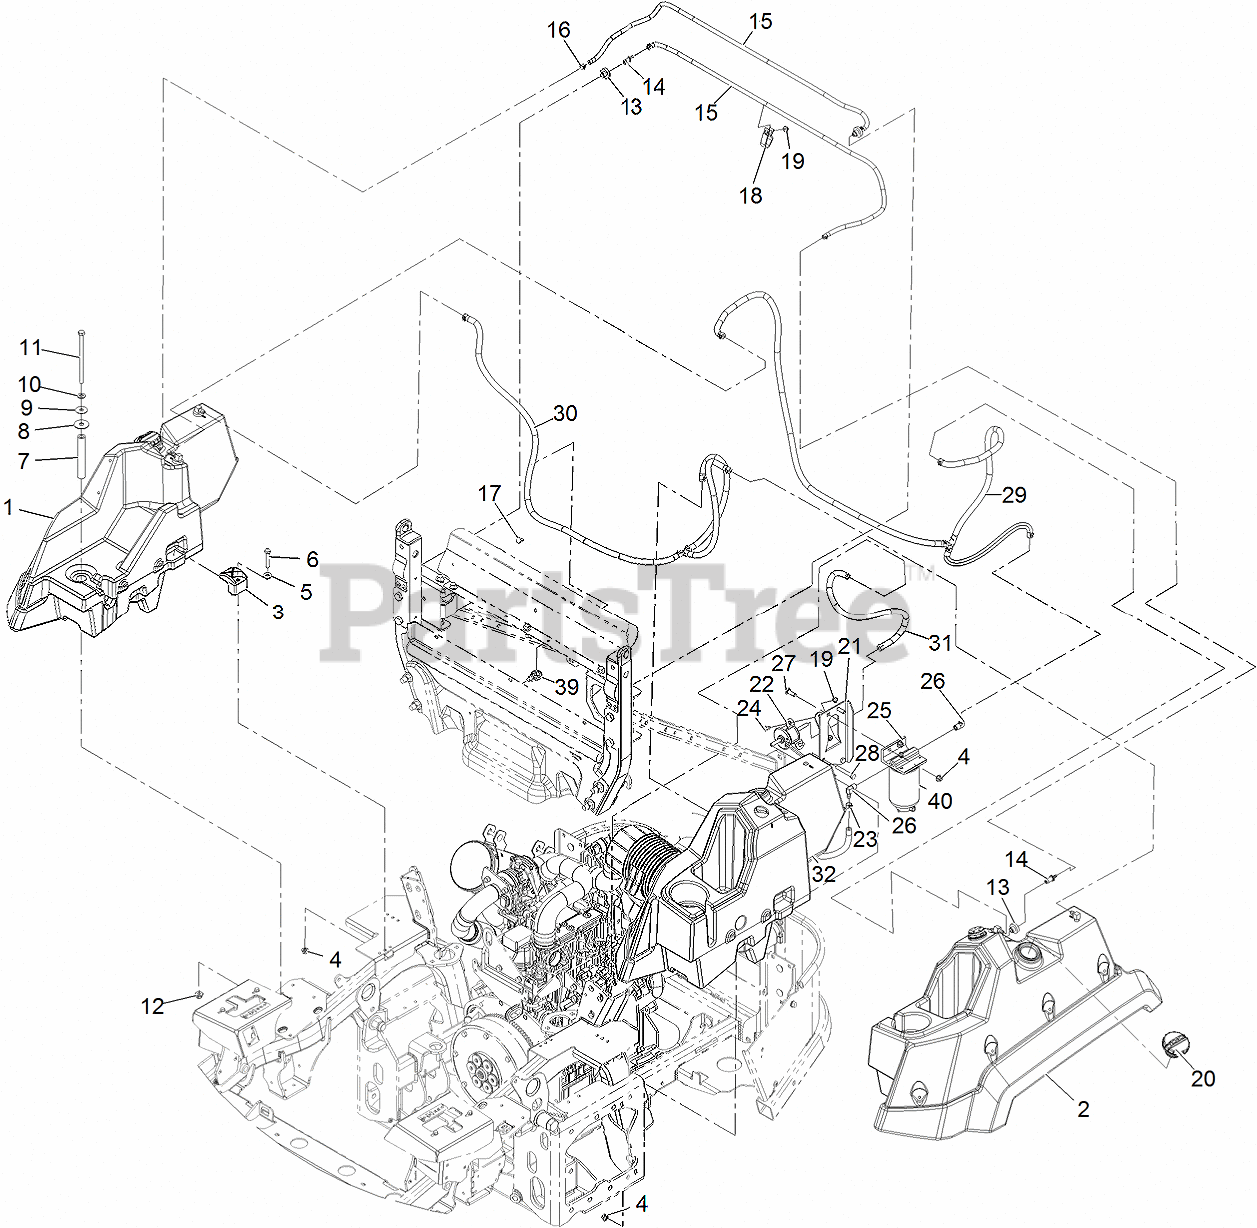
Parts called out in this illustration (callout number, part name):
1	RH FUEL TANK ASM
2	LH FUEL TANK ASM
4	NUT-HF, NI
5	WASHER-FLAT
6	SCREW-HH
7	TUBE-SPACER
8	WASHER-RUBBER
9	WASHER-PLAIN
10	WASHER-FLAT
11	SCREW-HH
12	NUT-HF, NI
13	BUSHING
14	FITTING-ORIFICE, STRAIGHT
15	HOSE-VENT, TANK
16	CLAMP-HOSE
17	SCREW-CARR
18	CLAMP-HOSE
20	CAP-FUEL, DIESEL
21	BRACKET-FILTER AND PUMP,
22	PUMP-FUEL, ELECTRIC
23	CLAMP-HOSE
24	SCREW-HWH
25	ASM,Fuel Filter W/Head
26	FITTING-HYD, 90
27	SCREW-CARR
28	SCREW-HH
29	LINE-FUEL, SUCTION
30	LINE-FUEL, RETURN
31	HOSE-FUEL
32	HOSE-FUEL
39	CLIP-TIE
40	FILTER-FUEL
